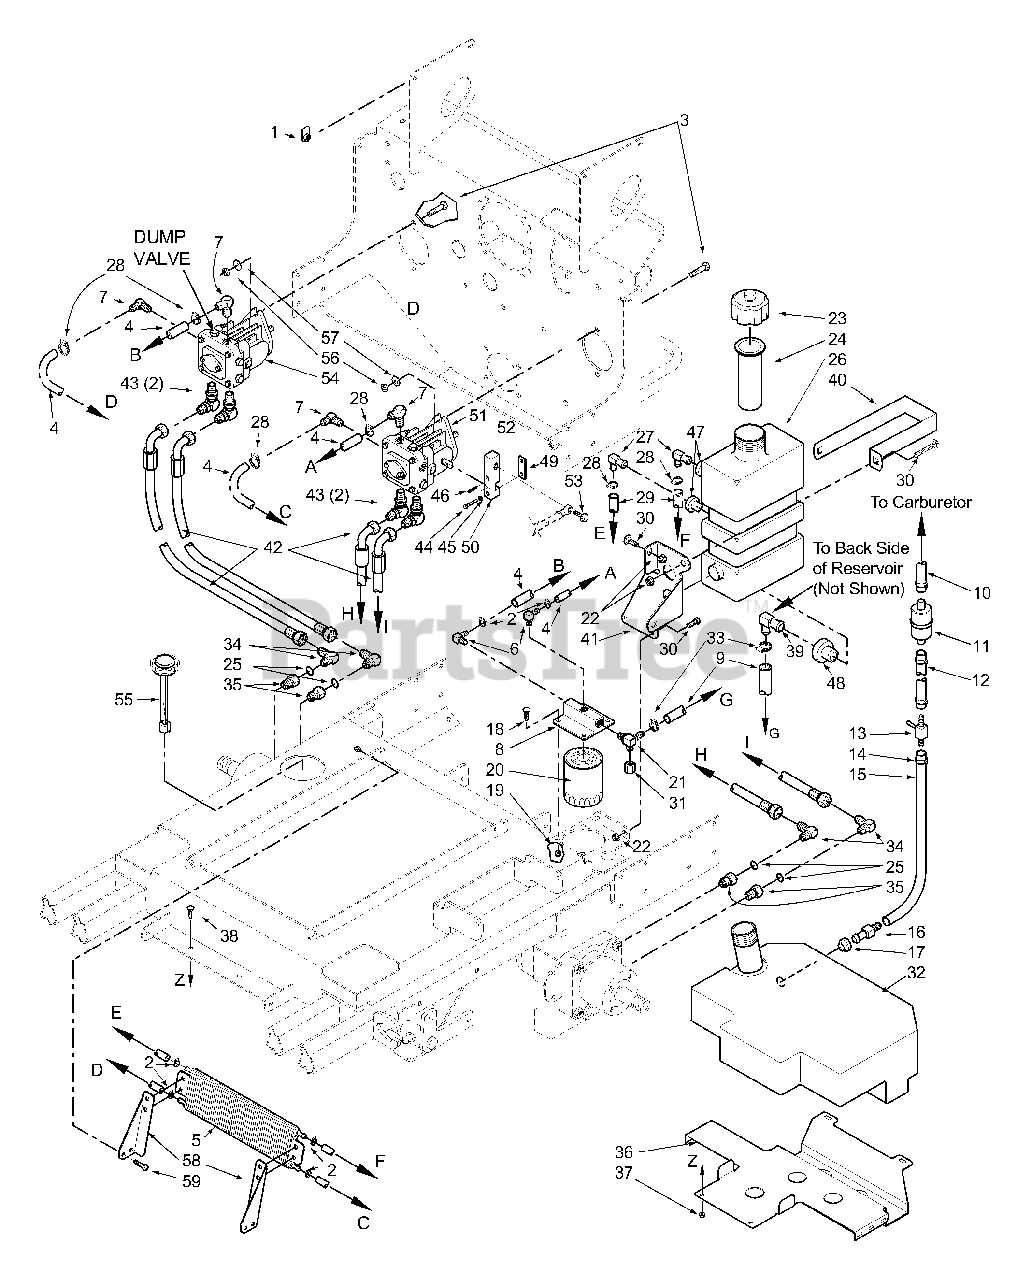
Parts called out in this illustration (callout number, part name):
1	U-Nut 1/4-20
2	Hose Clamp, 0.69 dia.
3	Bolt, Hex Head 1/4-20 x 2.0"
4	Hose, 3/8" ID Pushlock -
5	Cooler, Oil
6	Elbow, 90 Degree - 9/16 O-ring x 3/8 Hose
7	Elbow, 90 Degree - 3/4 O-ring x 3/8 Hose
8	Oil Filter Base
9	Hose Assembly, 1/2" ID (Tank to Filter Base)
10	Fuel Hose to Carb., 1/4" ID
11	Fuel Filter
12	Fuel Hose, 1/4" ID.
13	Valve, Shutoff
14	Clamp, Fuel Hose 7/32 ID
15	Fuel Hose, 1/4" ID.
16	Hose Fitting
17	Bushing
18	Bolt, Hex Head 5/16-18 x1.0" Zinc
19	Nut, Serrated Flange 5/16-18
20	Oil Filter
21	Tee, 3/4 O-ring x JIC x 1/2" Hose
22	Nut, Hex Elastic Stop 1/4-20
23	Cap, Hydraulic Tank
24	Insert, Filler Neck
25	O-Ring
26	Oil Reservoir Assembly
27	Elbow, 90 Degree, 9/16-18 JIC x 9/16 O-Ring
28	Hose Clamp, 0.69 dia.
29	Hose, 3/8" ID, Pushlock
30	Screw, Phillips Head, 1/4-20
32	Fuel Tank Assembly
33	Clamp, Hose
34	Elbow, 90 Degree, 7/8-14 THD
35	Bushing, 7/8-14 JIC x 3/4-16 O-Ring
36	Support Bracket, Fuel Tank
37	Nut, 5/16-18 Serrated Flange
38	Bolt, Carriage 1/4-20 x 3/4"
39	Elbow, 90 Degree
40	Strap, Hydraulic Tank
41	Support Bracket, Hydraulic Tank
42	Hose Assembly, Pump
43	Elbow, 90 Degree 7/8-14 Thread
44	Bolt, Hex Head, 1/4-20 x 1-14"
45	Lockwasher, 1/4" Spring
46	Roll Pin, Spring 3/16 x 3/4"
47	Bushing, .56 Dia.
48	Bushing, .78 Dia.
49	Clamp Plate, Pump Control
50	Block, Pump Control
51	Pump, Left Hand, BDP-21L-305
52	Nut, Hex, Elastic Stop 3/8-16
53	Bolt, Hex Head, 3/8-16 x 1-1/4
54	Pump, Right Hand, BDP-21L-403
55	Cap, Fuel Tank W/Guage
56	Nut, Hex Elastic Stop 3/8-16
57	Flatwasher, 3/8" (.391 x .938 x .105) Grade 8
58	Mounting Bracket - LH, Oil Cooler
59	Bolt, Hex Head 5/16-18 x 3/4"
